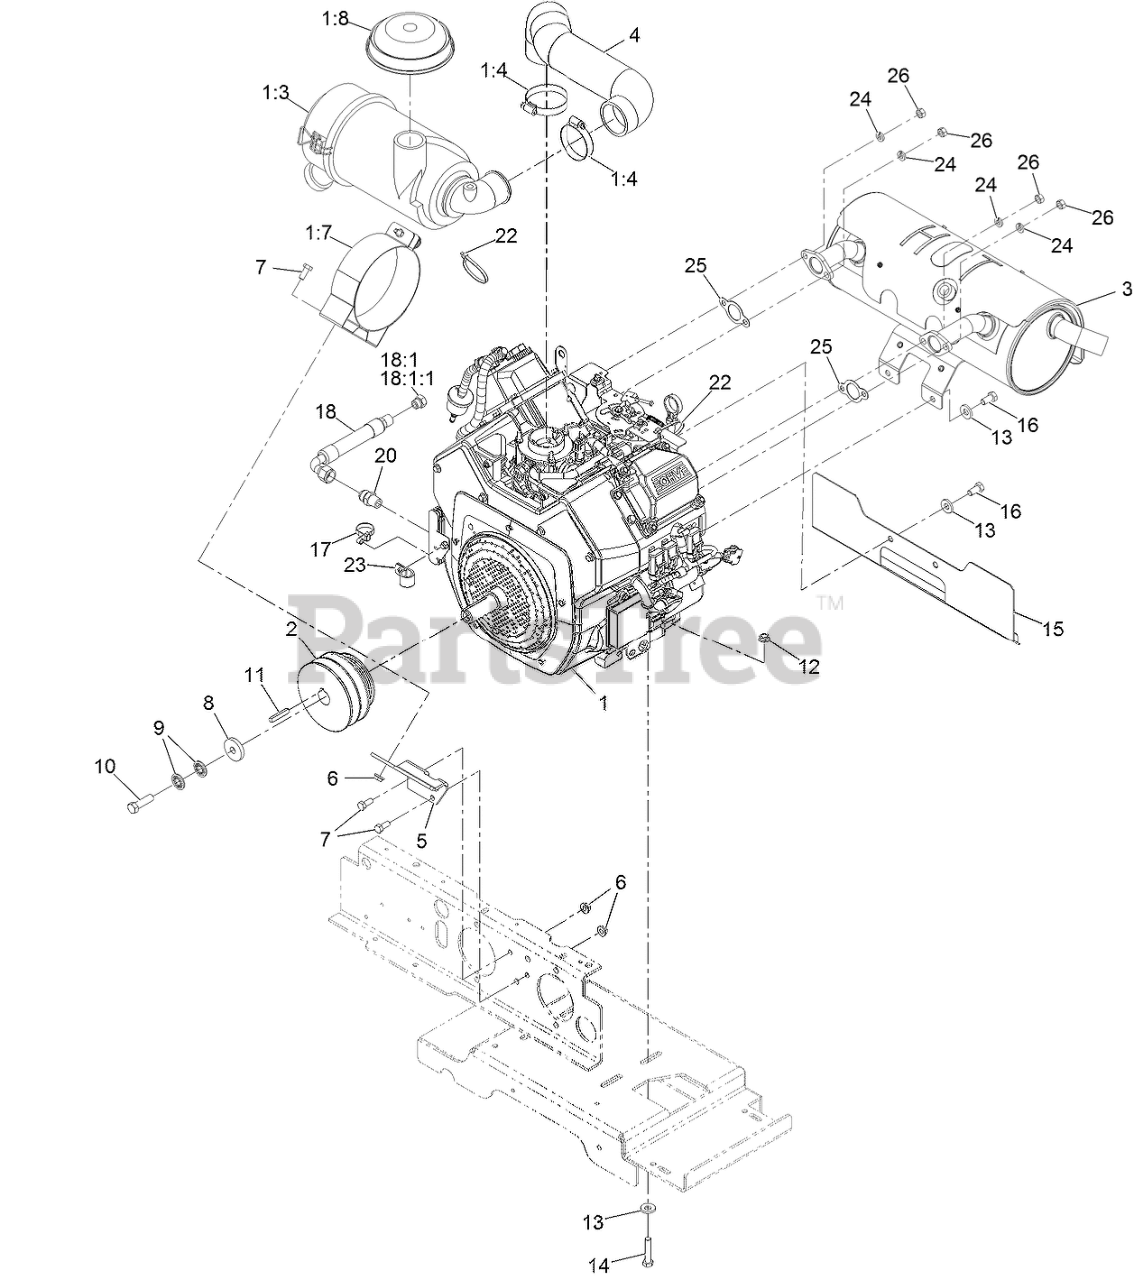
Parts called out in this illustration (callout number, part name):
1:3	AIR CLEANER CANISTER ASM
1:4	CLAMP-HOSE
1:7	BRACKET-FILTER, AIR
1:8	HOOD-CLEANER, 2" AIR INTA
4	HOSE-AIR INTAKE
5	BRACKET-FILTER, AIR
7	SCREW-HH
8	WASHER-CLUTCH
9	WASHER-SPRING
10	SCREW-HH
11	KEY-SQUARE
12	NUT-HHF, WHIZ
13	WASHER-BELLEVILLE
14	SCREW-HH
15	SHIELD-EXHAUST
16	SCREW-HH
17	Tie, Cable
18	OIL DRAIN HOSE ASM
18:1	PLUG-HH
18:1:1	O-RING
20	FITTING-STRAIGHT
22	TIE-CABLE
23	CLIP-LOOM
24	WASHER-LOCK
25	GASKET (KOHLER)
26	NUT-HEX
